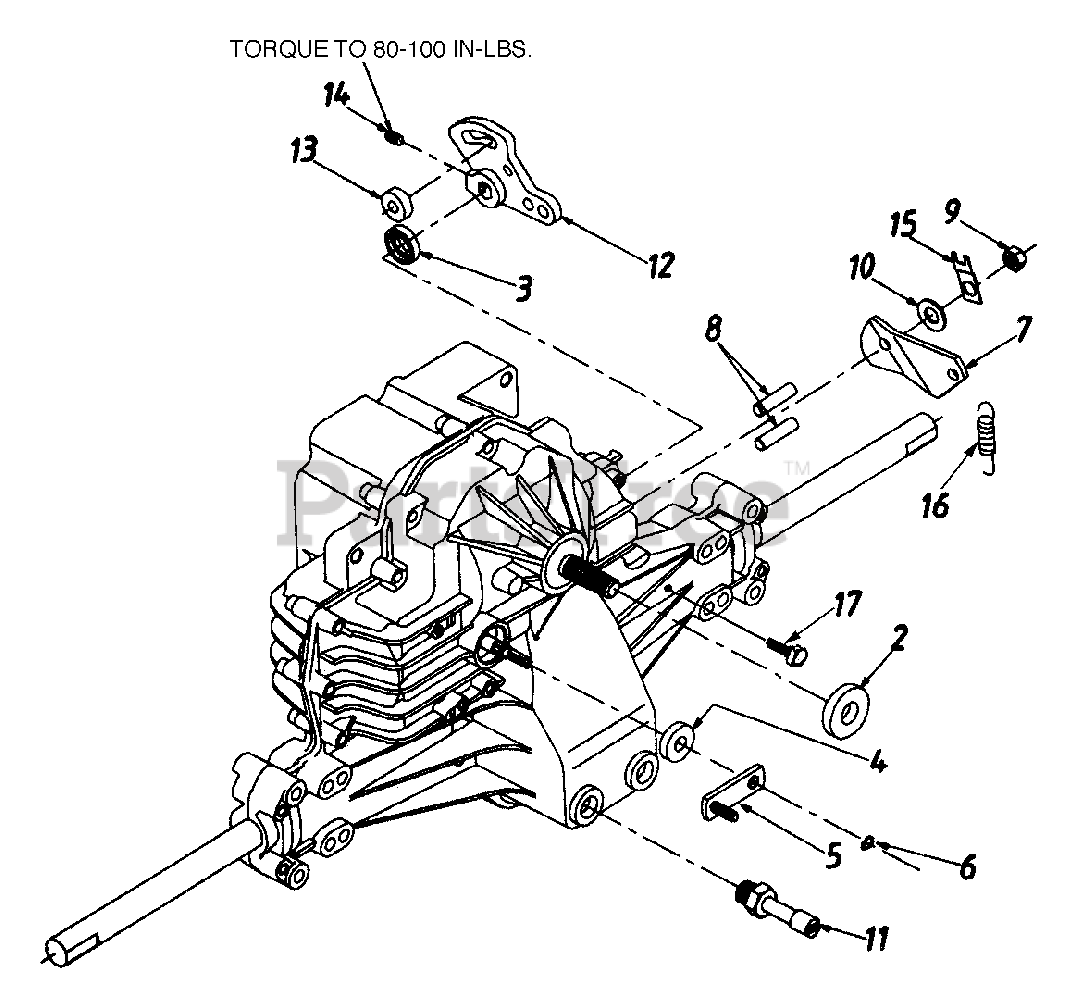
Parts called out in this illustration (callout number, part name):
4	Seal-Lip 10X25X7
6	Ring-Retaining
7	Arm-Actuating
8	Pin-Actuating
9	Nut-Hex Lock 5/16-24 UNJC
10	Washer 7/16" x 7/8" x .06"
11	Breather Ass'y.
13	Puck-Dampener
14	Set Screw
15	Strap, Locking
16	Spring, Extension
17	Self Tapp. Scr. #10-.325 x .5"
